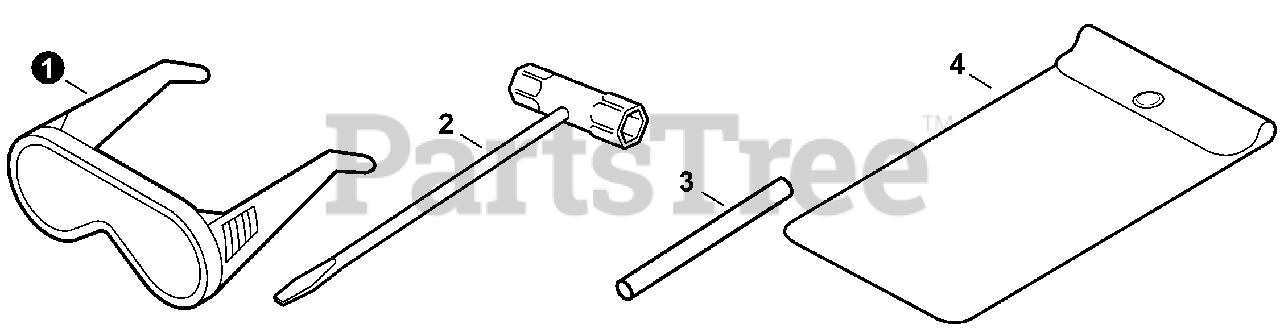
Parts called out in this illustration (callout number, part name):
1	GLASSES, SAFETY
2	T-WRENCH 17x-19 L200
3	TOOL, LOCKING 5×120 MM
4	BAG, TOOL
